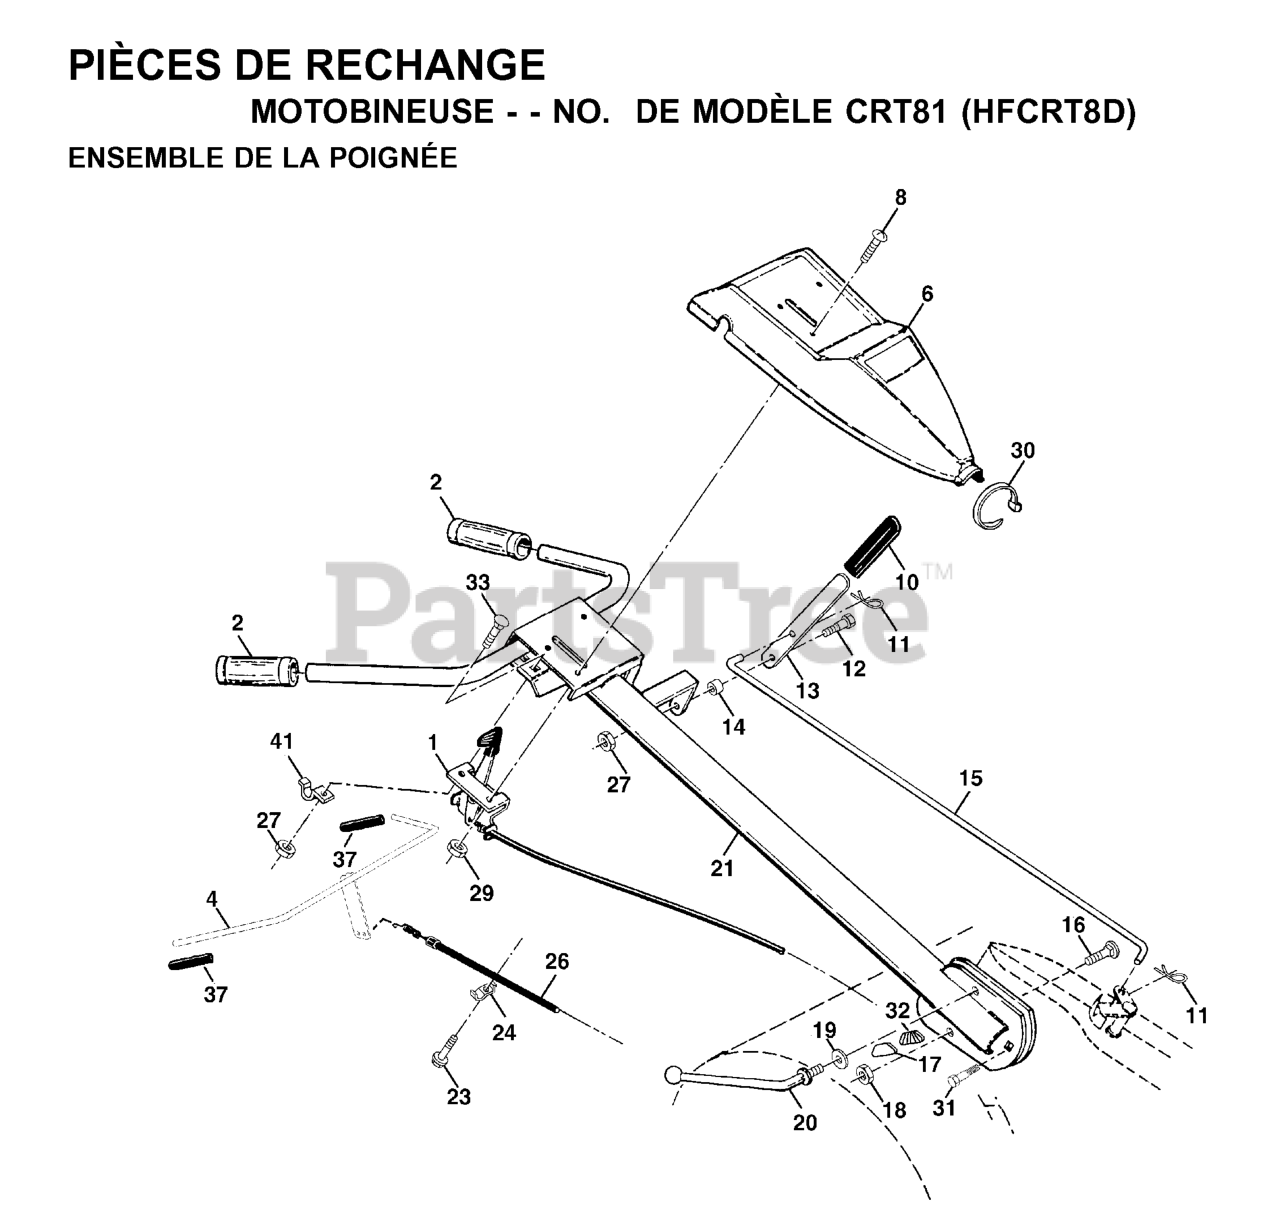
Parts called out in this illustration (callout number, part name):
1	THROTTLE CONTROL
2	KIT.GRIP.HANDLE.5.00.BLK.VINYL
4	CONTROL BAR ASSY
8	SCREW.PNHD.10-24
10	GRIP T
11	RETAINER M
12	SHOULDER BOLT ST
13	SHIFT HANDLE CRT
14	GROMMET.RUBBER.CRT.TILLER
15	ROD.SHIFT.YARD PRO.UNIVERSAL.
16	BOLT D
17	LOCK.HANDLE.CRT
19	WASHER CRT
20	LEVER.LOCK.CRT
21	HANDLE
23	SCREW.HEX.WSH.SLT.#10-24X.50
24	CONDUIT.CLIP.PLATED
26	CABLE.CLUTCH
27	NUT T
29	NUT **
30	TIE CABLE CRT
31	BOLT.PIVOT
32	LOCK HANDLE
37	GRIP BAR CRT(1)
41	CLAMP.BAR.CRT.BLACK
